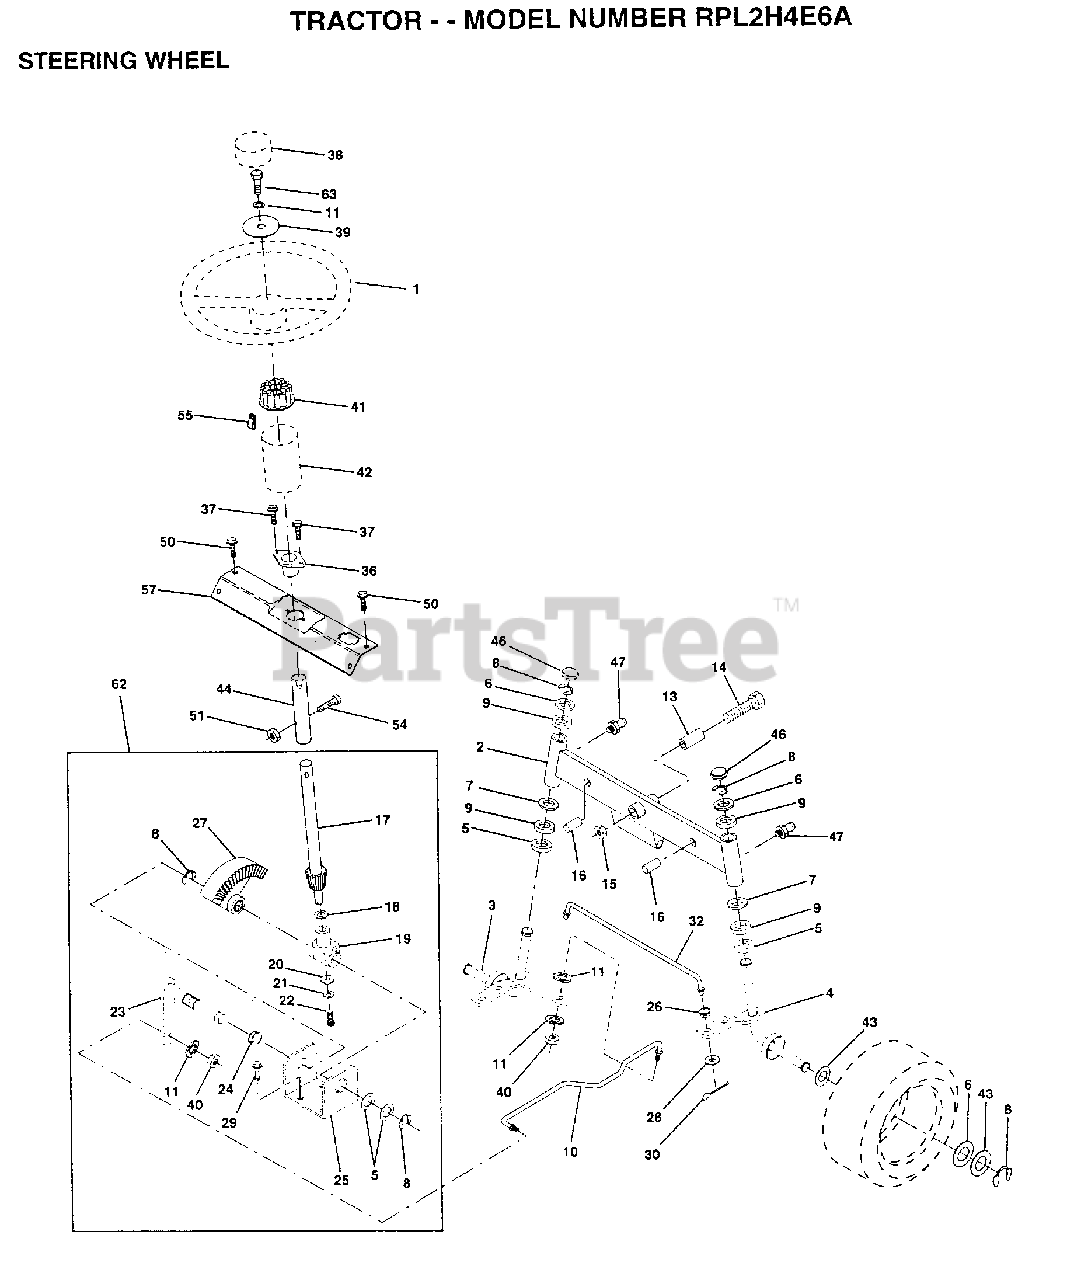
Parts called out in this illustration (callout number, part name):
2	AXLE ASM FRONT
3	SPINDLE LH
4	SPINDLE RH
5	WASHER .T
6	WASHER
7	WASHER
8	RING
9	COL. SRTG. BEAR.
11	LOCKWASHER
13	BEARING
14	BOLT HEX 5/8-11
15	"NUT-LOC,FLANGE LT"
16	AXLE PIN
17	SHAFT ASM STEERIN
18	THRUST WASHER
19	SUPPORT.SHAFT
21	LOCKWASHER
22	SCREW.SCKTHD.CAP
24	NYLINER T
25	"BRKT,STEERING"
26	BUSHING.DRAGLINK
27	GEAR SECTOR
28	WASHER
29	SCREW
30	COTTER PIN
32	TIE ROD
37	"SCREW-TT,10-32 FL"
38	ST WHL INSERT CAP
39	WASHER T
40	GRIPCO NUT
41	ADAPTER LT
42	BOOT SHAFT STEER
43	WASHER
44	SHAFT EXT STEERIN
46	CAP
47	ZERK M
50	SCREW HEX CRT
51	NUT
54	BOLT
55	CLIP TINNERMAN
57	SUPPORT SHAFT STR
63	BOLT
